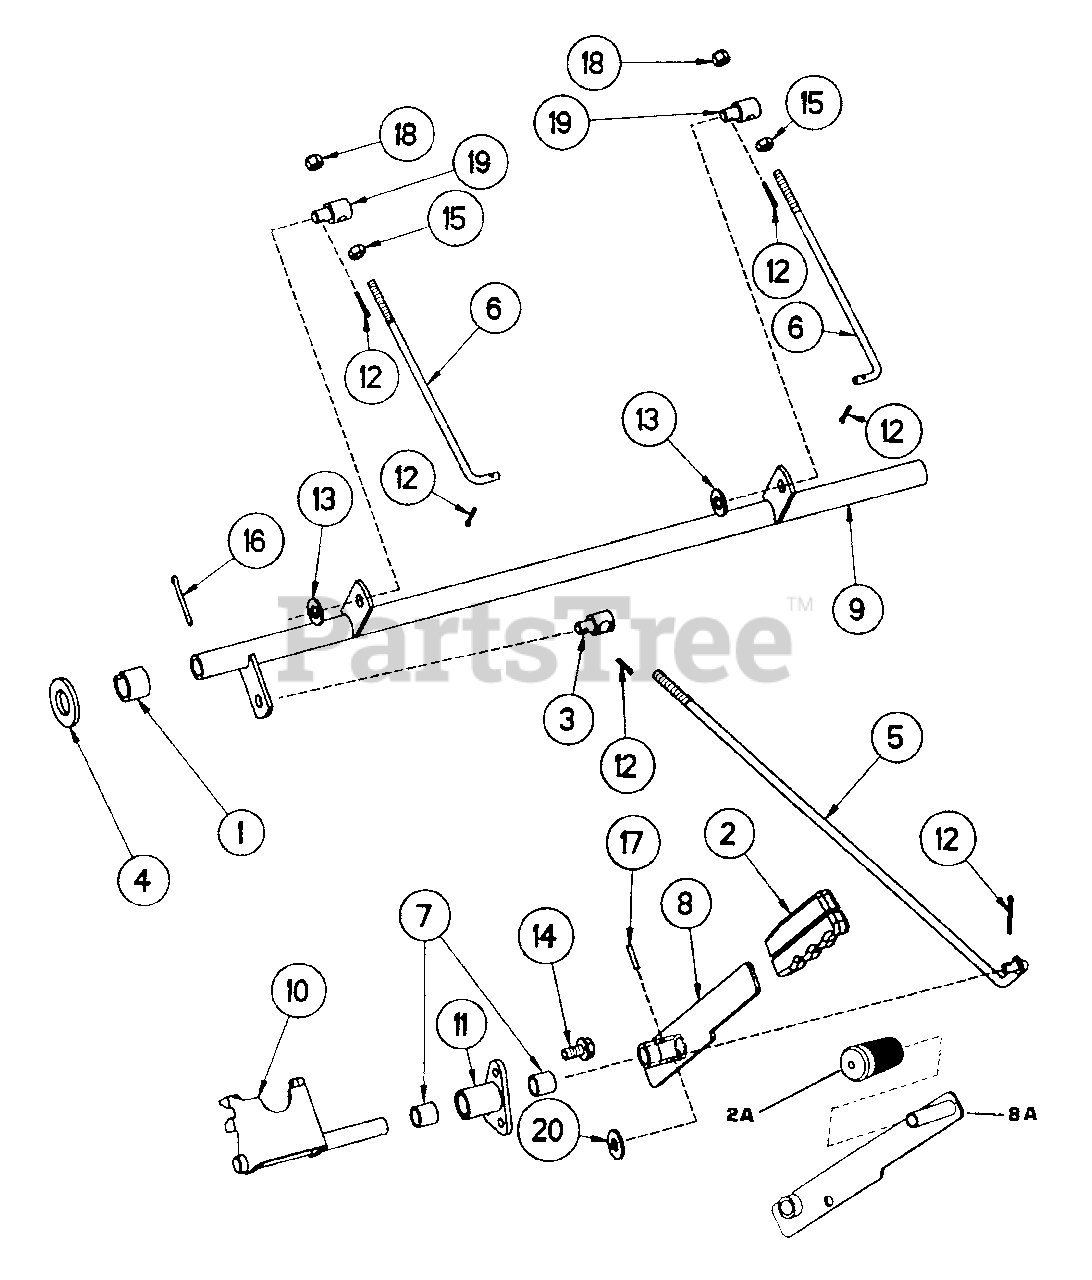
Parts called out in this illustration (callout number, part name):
1	RING, Rear Lift Arm
2	GRIP, Flat Bar (21 HP Diesel Engine)
2A	GRIP, Round Bar (23 HP Gas Engine)
3	SWIVEL, Adjustable
4	WASHER, 3/4 I.D. x 1-1/2 O.D. x 9/64" Flat
5	ARM, Brake Lift
6	ROD, Hydrostatic Brake
7	SLEEVE Bearing, 1/2 I.D. x 5/8
8	ARM, Parking Brake (21 HP Diesel Engine)
8A	ARM, Parking Brake (23 HP Gas Engine)
9	SHAFT, Brake
10	BRACKET, Joystick Lockout
11	PLATE, Support
12	COTTER PIN, 3/32 x 3/4"
13	WASHER, 3/8" Flat
14	SCREW, 5/16-18 x 5/8" Hex Washer Face Self-Tap
15	NUT, 1/4-28 Hex, Grade 5 or B
16	COTTER PIN, 1/8 x 1-1/4
17	PIN, Roll 1/8 x 3/4"
18	NUT, 1/4-28 Hex Nyloc
19	SWIVEL, 1/4" Smooth
20	WASHER, 3/8" I.D. x 7/8" O.D. Flat
